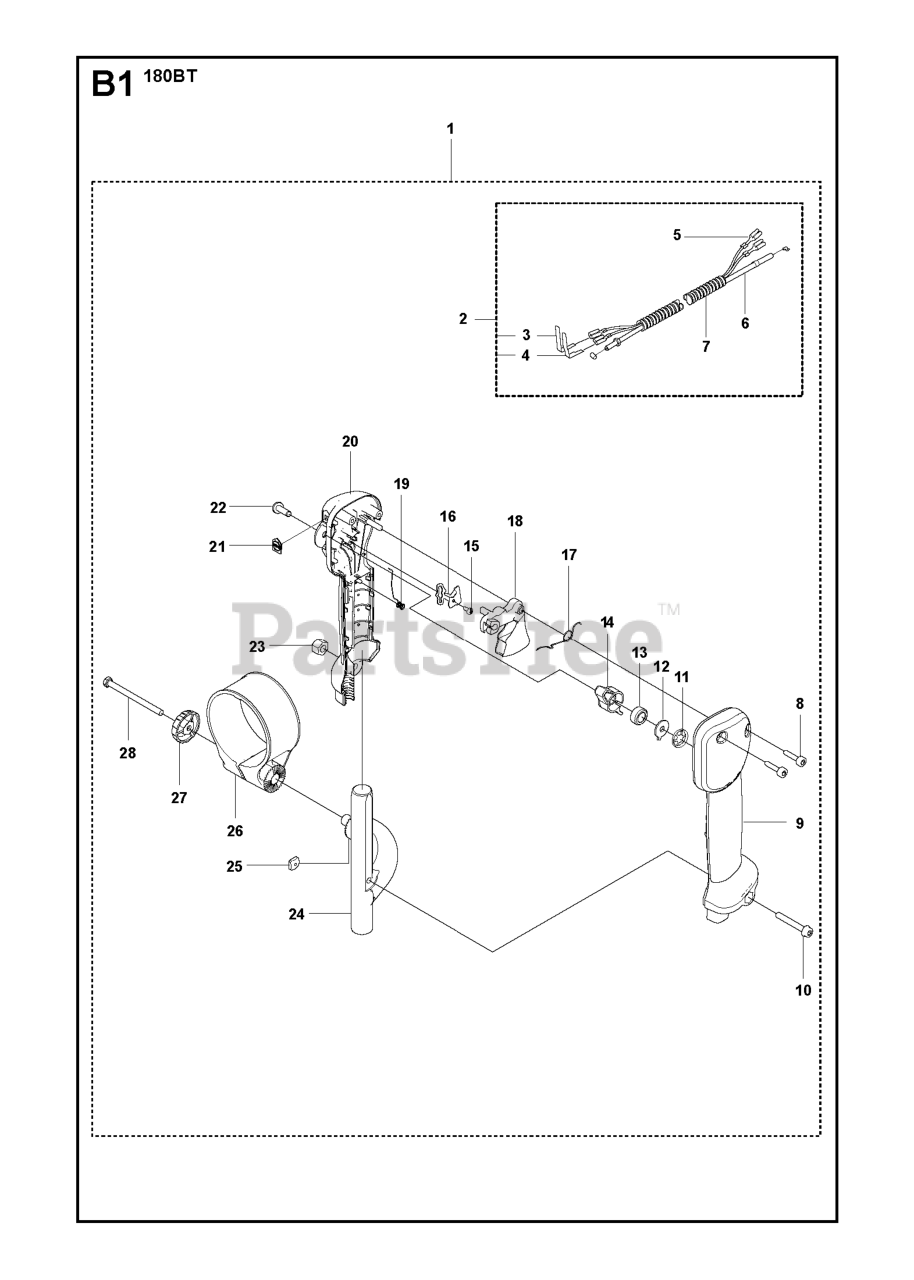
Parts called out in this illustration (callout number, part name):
1	LEVER SET
2	THROTTLE CABLE
3	CONTACT SPRING
4	CONTACT SPRING
9	HANDLE HALF (R)
13	SPRING RUBBER
14	LEVER STOP
18	TRIGGER 848L5W34C0
20	HANDLE HALF (L)
22	SHAFT PIVOT
24	HOLDER, HANDLE
26	HOLDER TH
27	KNOB
